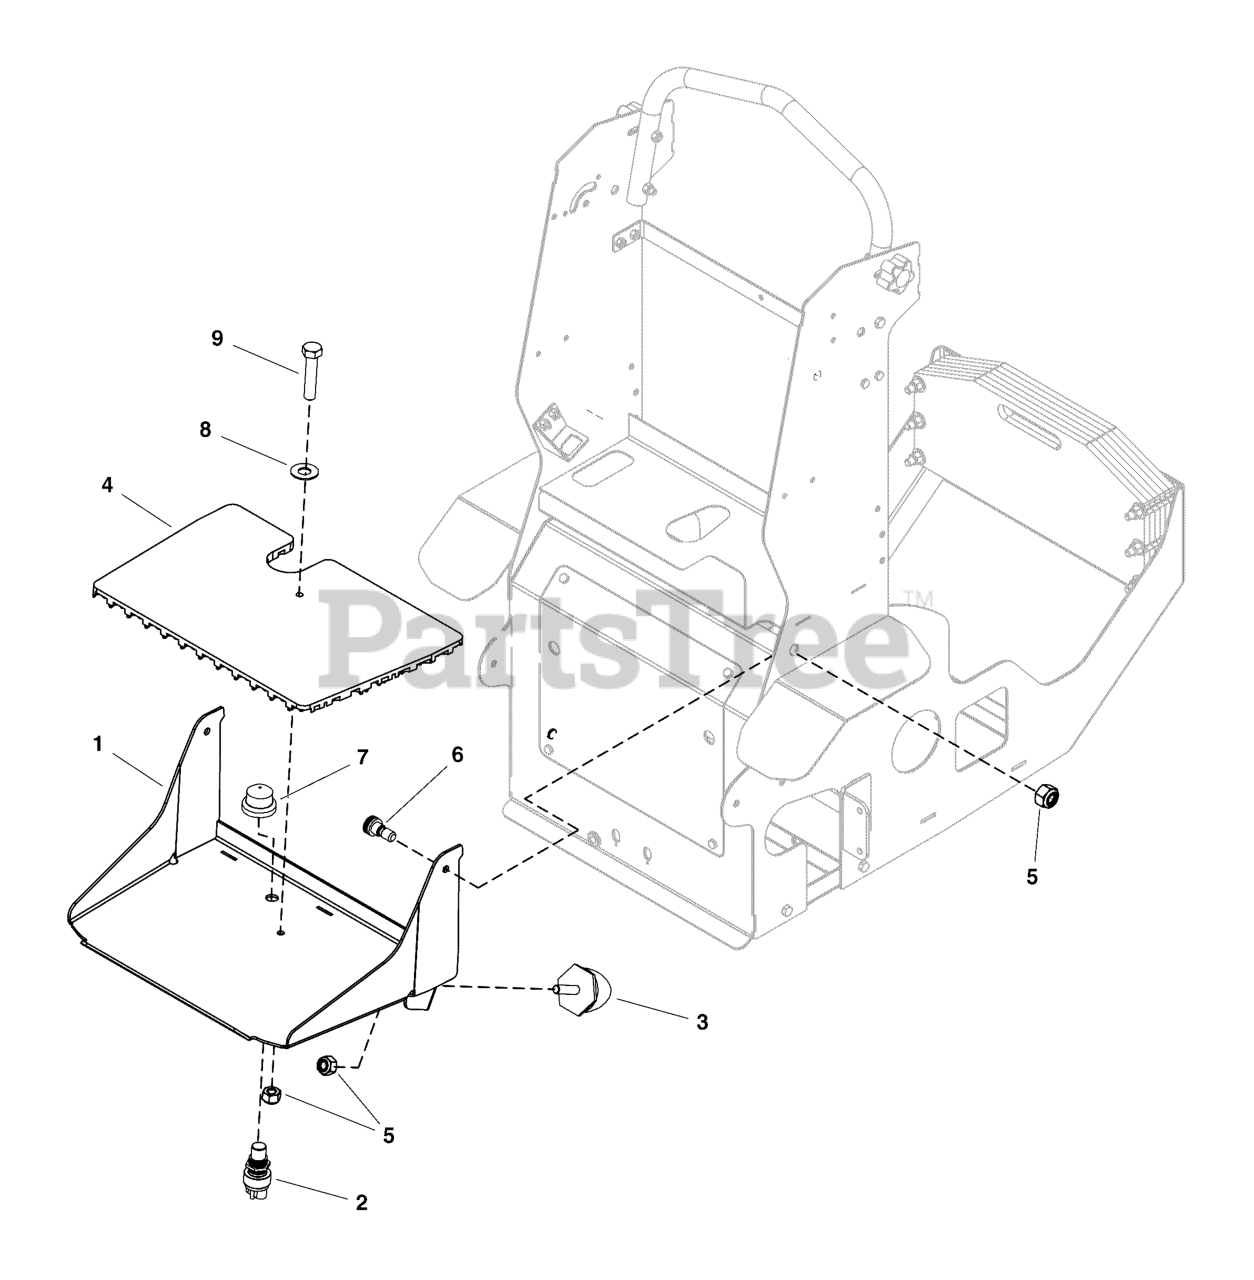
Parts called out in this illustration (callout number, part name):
1	WELD, FOOTPAN
2	SWITCH, MOMENTARY 60A 12VDC
3	BUMPER, MALE TAPERED 5/16-18 THD, 140 LB
4	PAD, FOOT RUBBER
5	NUT-HEX-NYLK, 0.3125"-18 SS188
6	BLT-SLDR, SH .375" X 0.250", .3125"-18 X.500" SS188
7	BOOT, SWITCH 5/8-32 THREADED
8	WSHR-STL, FLT .406" X .875" X .050" IS SS188
9	SCR-CAP, HEX .3125"-18 X 1.500" SS188
